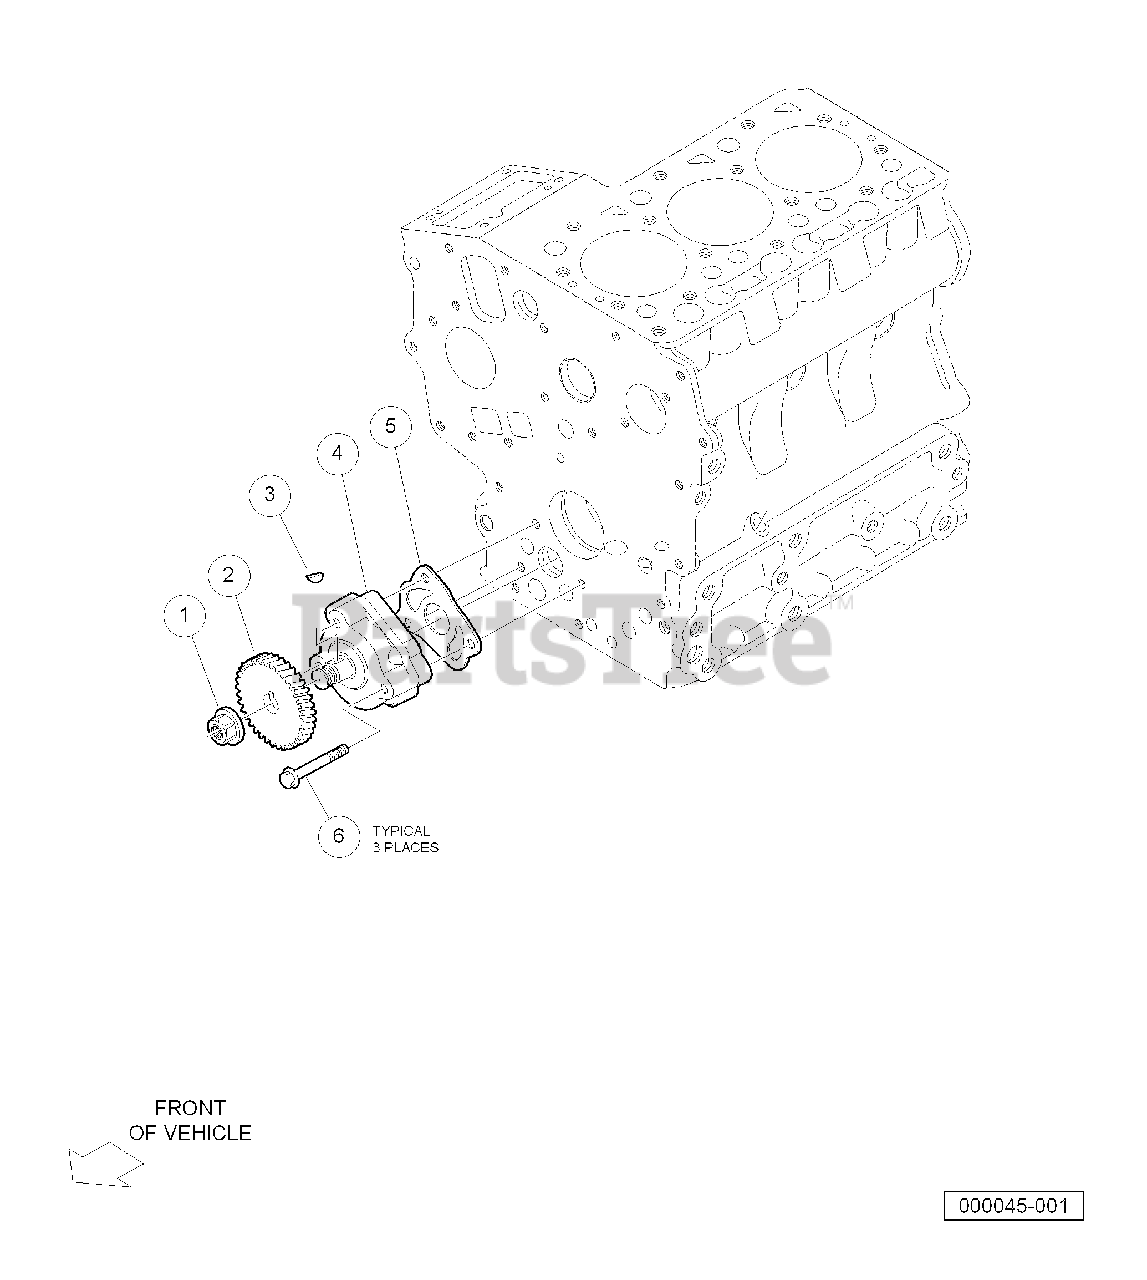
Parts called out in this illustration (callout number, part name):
1	Nut, Flange, D722 Oil Pump
2	Gear, Oil Pump Drive
3	Key, Feather, 8x4
4	Assy, Pump, Oil
5	Gasket, Oil Pump
6	Bolt, Oil Pump
